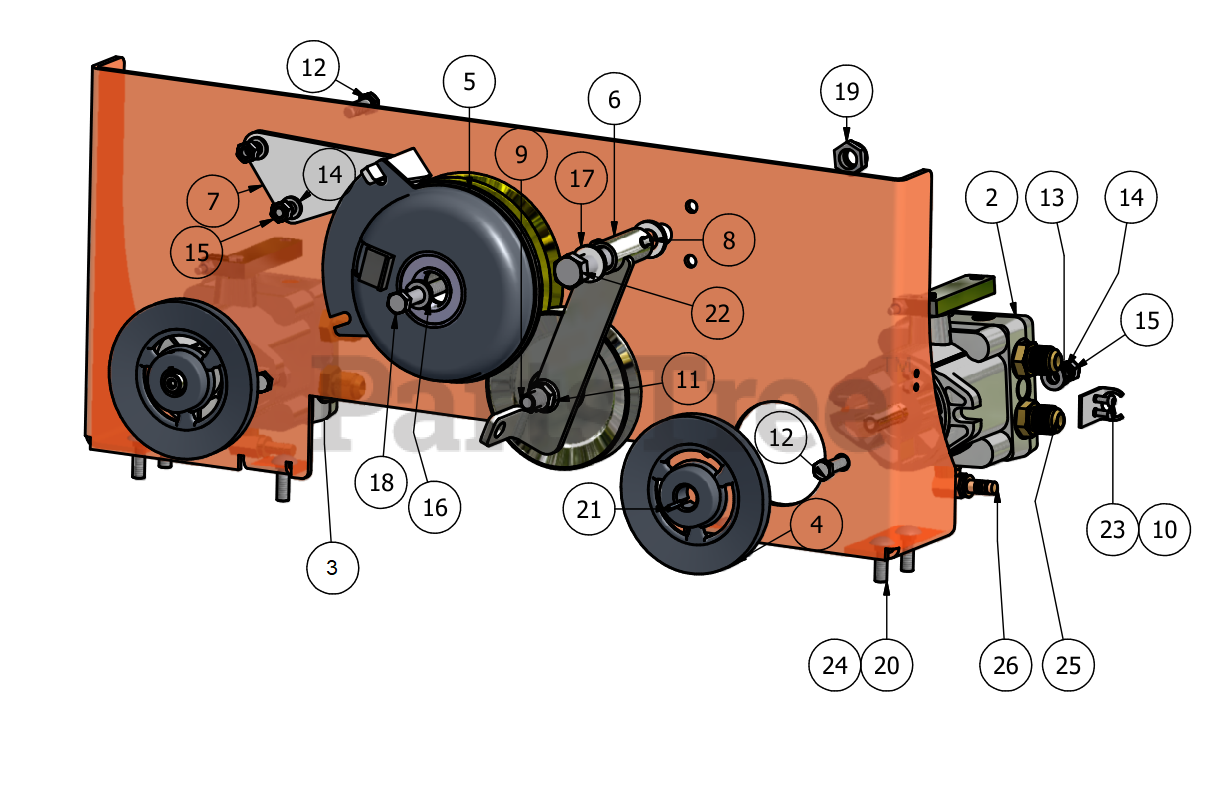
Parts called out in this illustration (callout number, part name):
2	Hydraulic Pump (Right)
3	Hydraulic Pump (Left)
4	5" Pump Pulley
6	Pump Idler Bracket
7	PTO Engager Holder
8	Grease Fitting (Drive-IN Type)
9	1/2" x 2 1/2" Hex Bolt
10	1024 Nylock Nut
11	1/2" Flange Nut
12	3/8" x 1 1/2" Hex Bolt
13	3/8" Flat Washer
14	3/8" Lock Washer
16	7/16" Lock Washer
17	.635 ID Plastic Washer
18	7/16" x 2 1/2" Fine Thread Bolt
19	5/8" Nylock (1/2 Jam)
20	3/8" x 1 1/4" Carriage Bolt
21	5mm x 1.25" Key
22	5/8" x 4" Hex Bolt
23	1024 x 1" Buttonhead Bolt
24	3/8" Nylock Nut
25	Hydraulic Fitting
26	3/8" X 9/16"-18 ORB Male Fitting (S,A-2 P-4)
